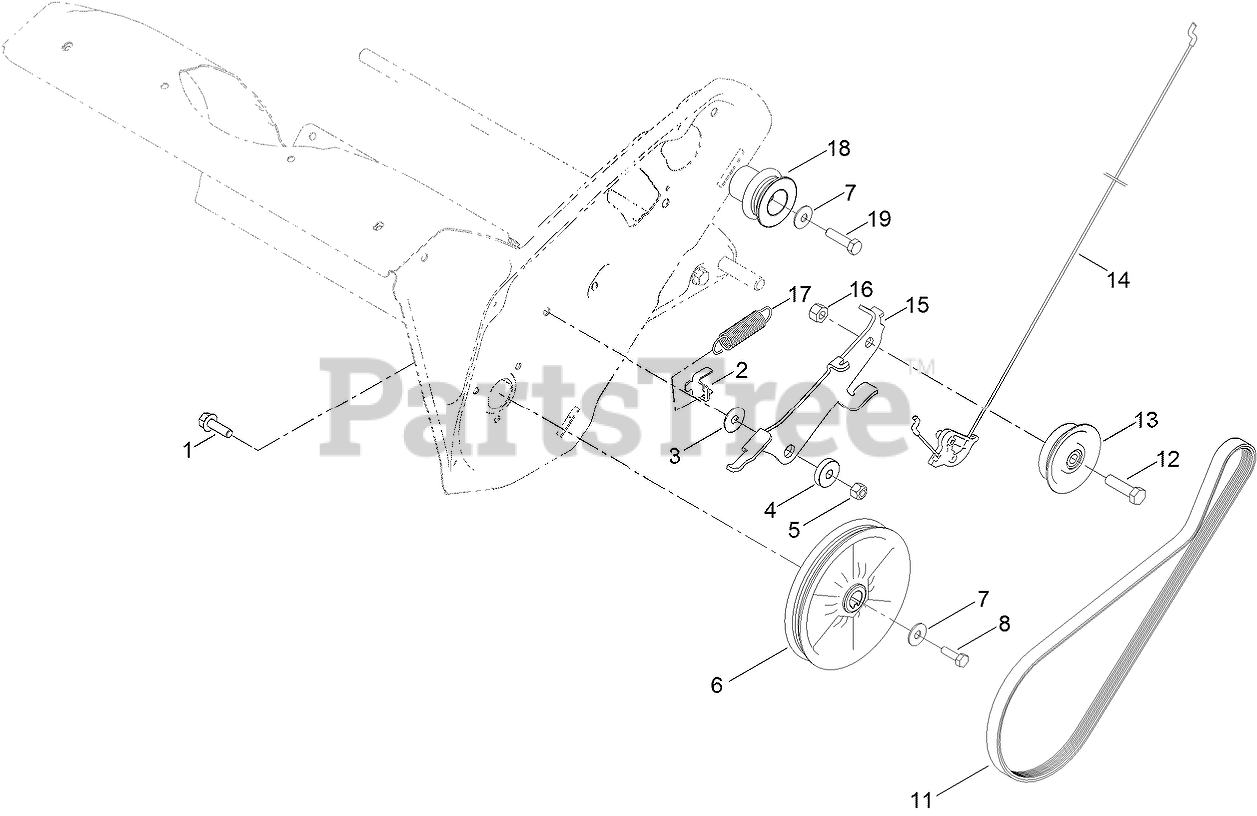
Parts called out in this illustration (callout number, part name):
1	SCREW-HHF
2	CLIP-SPRING
3	WASHER
4	BUSHING-PIVOT
5	NUT-HEX
6	PULLEY
7	WASHER-BELLEVILLE
8	SCREW-HH,LOCK
11	BELT-DRIVE
12	SCREW-HH
13	PULLEY-IDLER
14	CABLE-CLUTCH
15	ARM-IDLER
16	NUT-HEX
17	SPRING-EXTENSION
18	PULLEY-ENGINE
19	SCREW-HH LOCK
